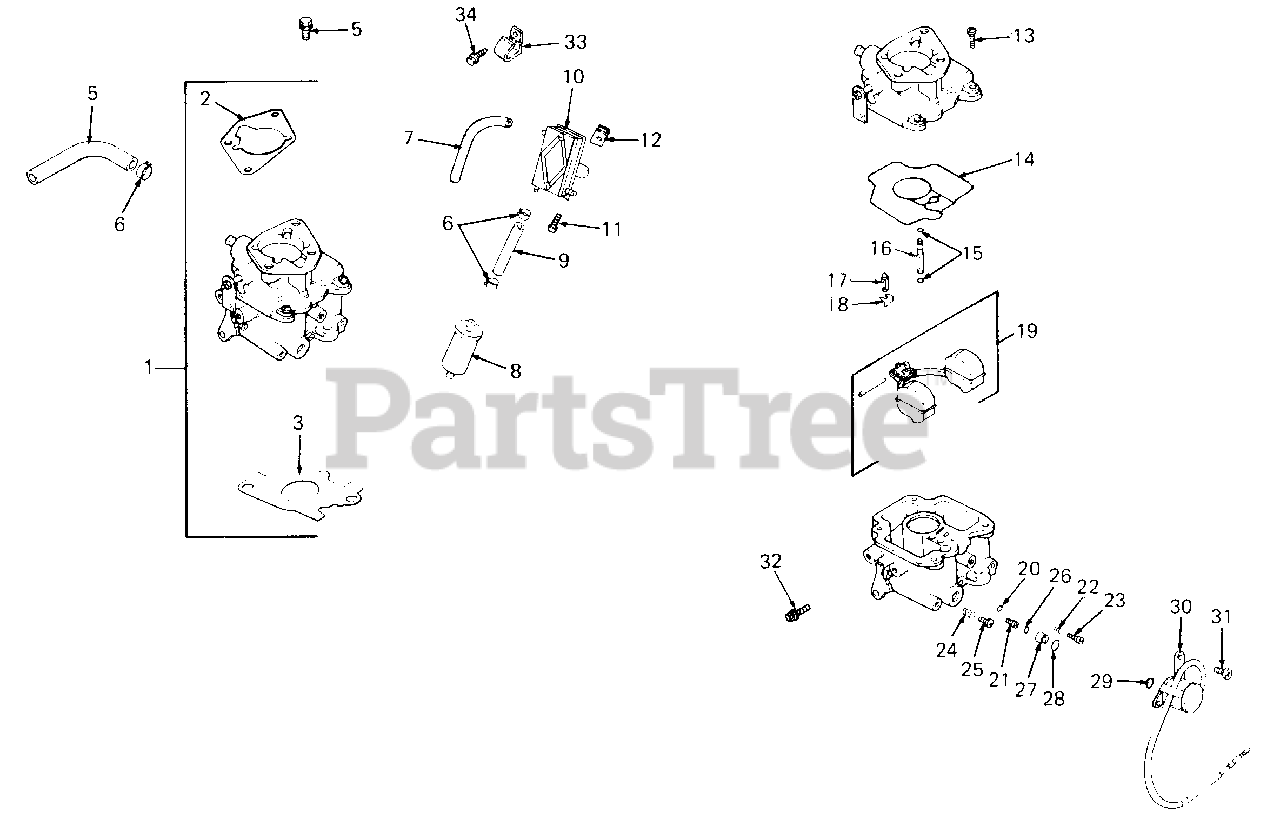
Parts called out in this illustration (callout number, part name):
1	Kit, Carburetor
2	Gasket, Air Cleaner
3	Gasket, Carburetor
5	Line, Fuel, 9"
6	Clamp, Hose
7	Line, Fuel, 15.5"
8	Filter, Fuel
9	Line, Fuel, 10"
10	Pump, Fuel-Pulse
11	Screw, Hex Cap
12	Nut
13	Screw, Carburetor Body
14	Gasket, Carburetor Body
15	O-Ring, Slow Jet
17	Valve, Inlet Needle
18	Clip, Inlet Needle Valve
19	Kit, Float Repair
20	O-Ring, Main Jet
22	Spring, Idle Adjust
23	Needle, Idle Adjust
24	Spring, Idle Speed Adjust
25	Screw, Idle Speed Adjust
27	Seat, Solenoid
29	O-Ring, Solenoid
30	Solenoid
32	Screw, Throttle Stop
33	Clip, Cable
34	Screw, M6 X 1.0 X 10
